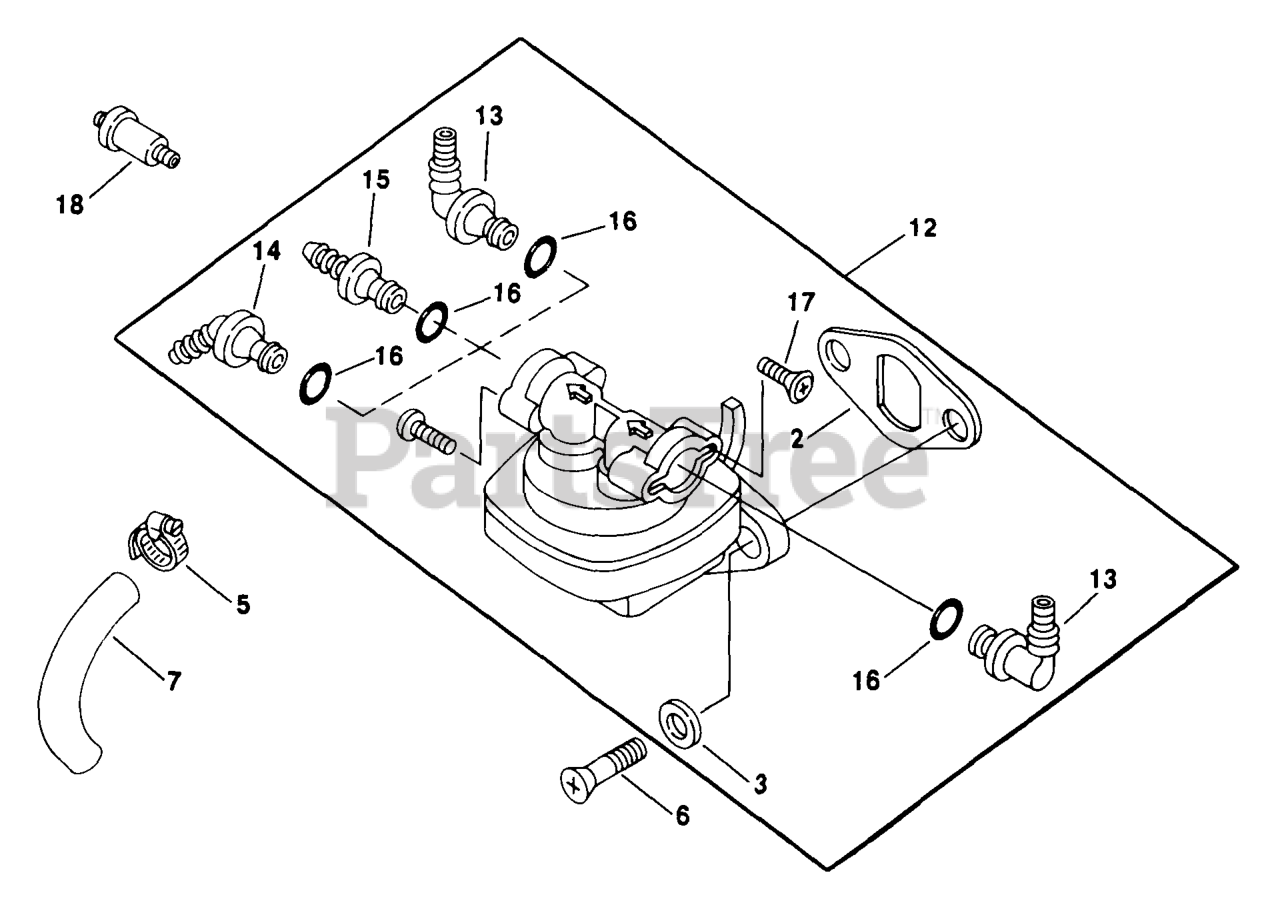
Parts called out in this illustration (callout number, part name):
2	GASKET - USE 25 041 09
3	WASHER, FLAT 1/4" (O.D. 1/2")
5	CLAMP, HOSE 1/2" USE 25 237 14-S
6	SCREW, SEMS 1/4-20X3/4"
7	LINE - DISCONTINUED
12	PUMP - USE 47 559 04-S
13	CONNECTOR, 90 DEG. W/O-RING-DISC.
14	CONNECTOR, 45 DEG. W/O-RING-DISC.
15	CONNECTOR,STRAIGHT W/O-RING-DISC.
16	O RING FITTING - DISCONTINUED
17	SCREW, LBD SCKT PAN - DISC.
